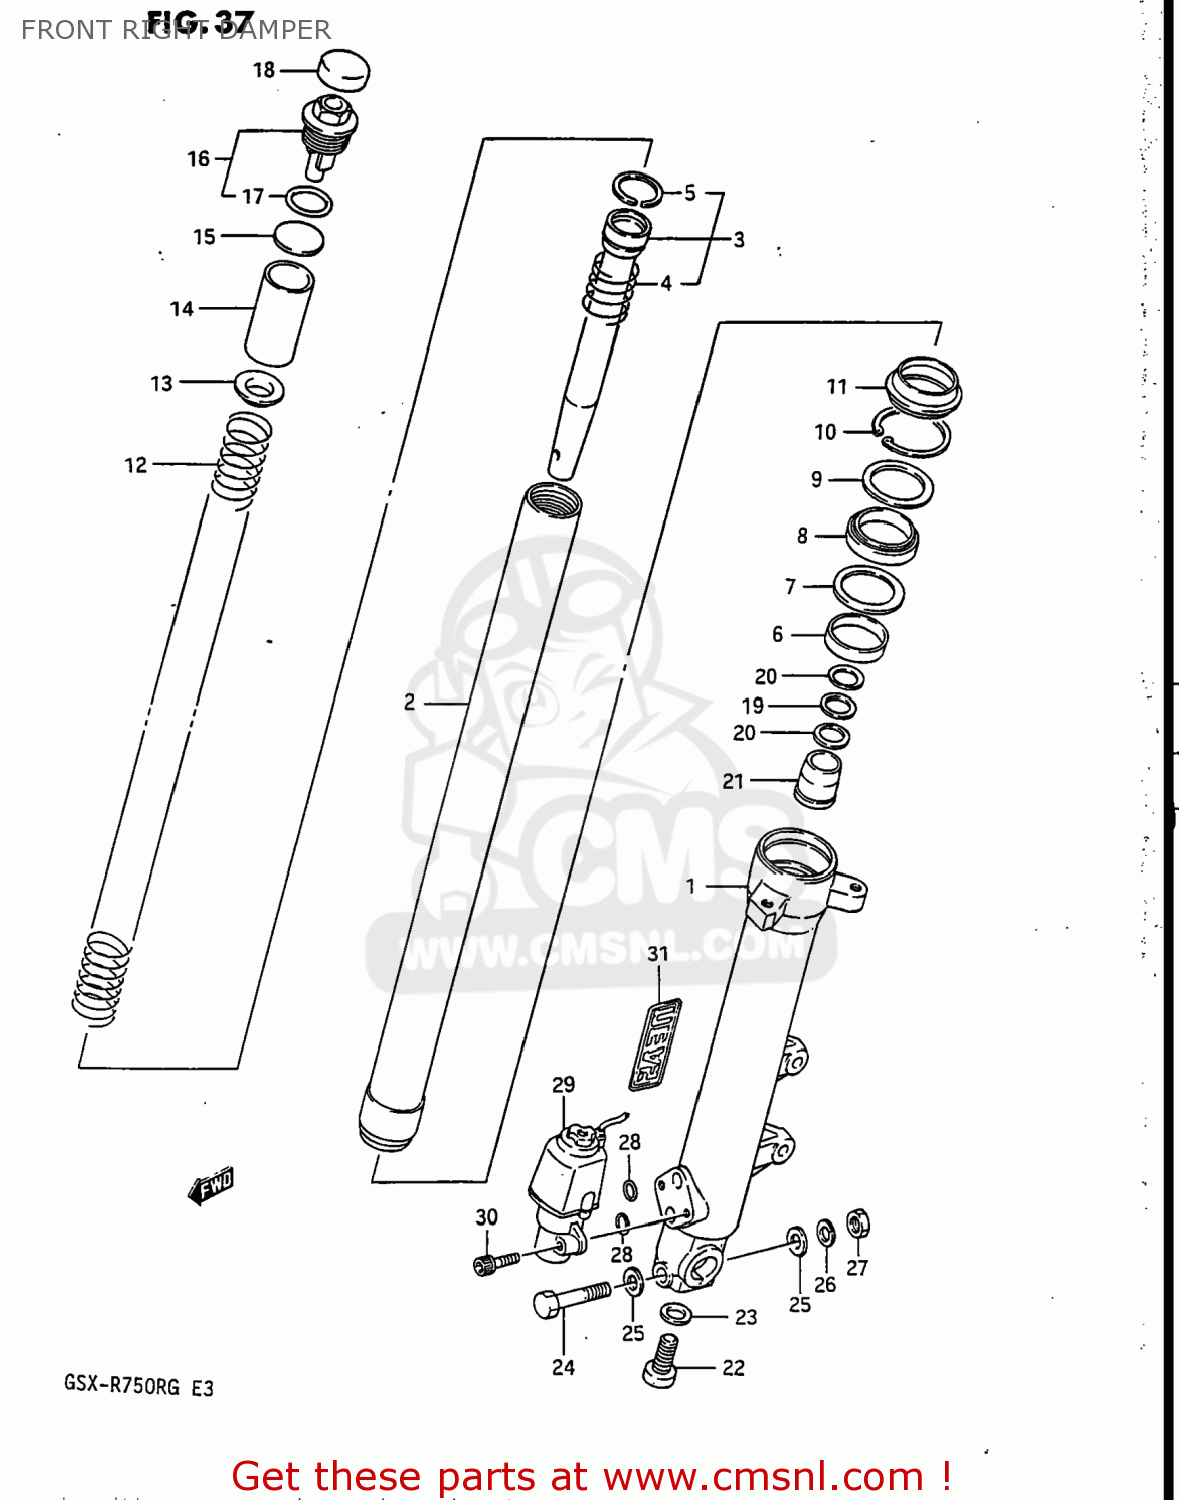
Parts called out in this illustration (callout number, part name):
1	TUBE,OUTER,RIGHT
2	TUBE,FORK INNER
3	CYLINDER
4	SPRING,REBOUND
5	RING,FR FORK PISTON
6	METAL,SLIDE
7	WASHER,FORK OIL SEAL
8	OIL SEAL,FRONT FORK
9	WASHER,FORK OIL SEAL
10	RING,OIL SEAL STOPPER
11	DUST SEAL,FRONT FORK
12	SPRING,FRONT FORK
13	WASHER
14	SPACER
15	WASHER,FR FORK SPRING
16	CAP,FORK INNER TUBE
17	O RING
18	CAP
19	WASHER,OIL LOCK PIECE
20	SPRING,FORK OIL LOCK PIECE
21	PIECE,OIL LOCK
22	BOLT(14X25)
23	GASKET (NAS)
24	BOLT 10X60
25	WASHER
26	LOCK WASHER
27	NUT
28	O RING
29	P.D.F. ASSEMBLY
30	BOLT
31	EMBLEM
